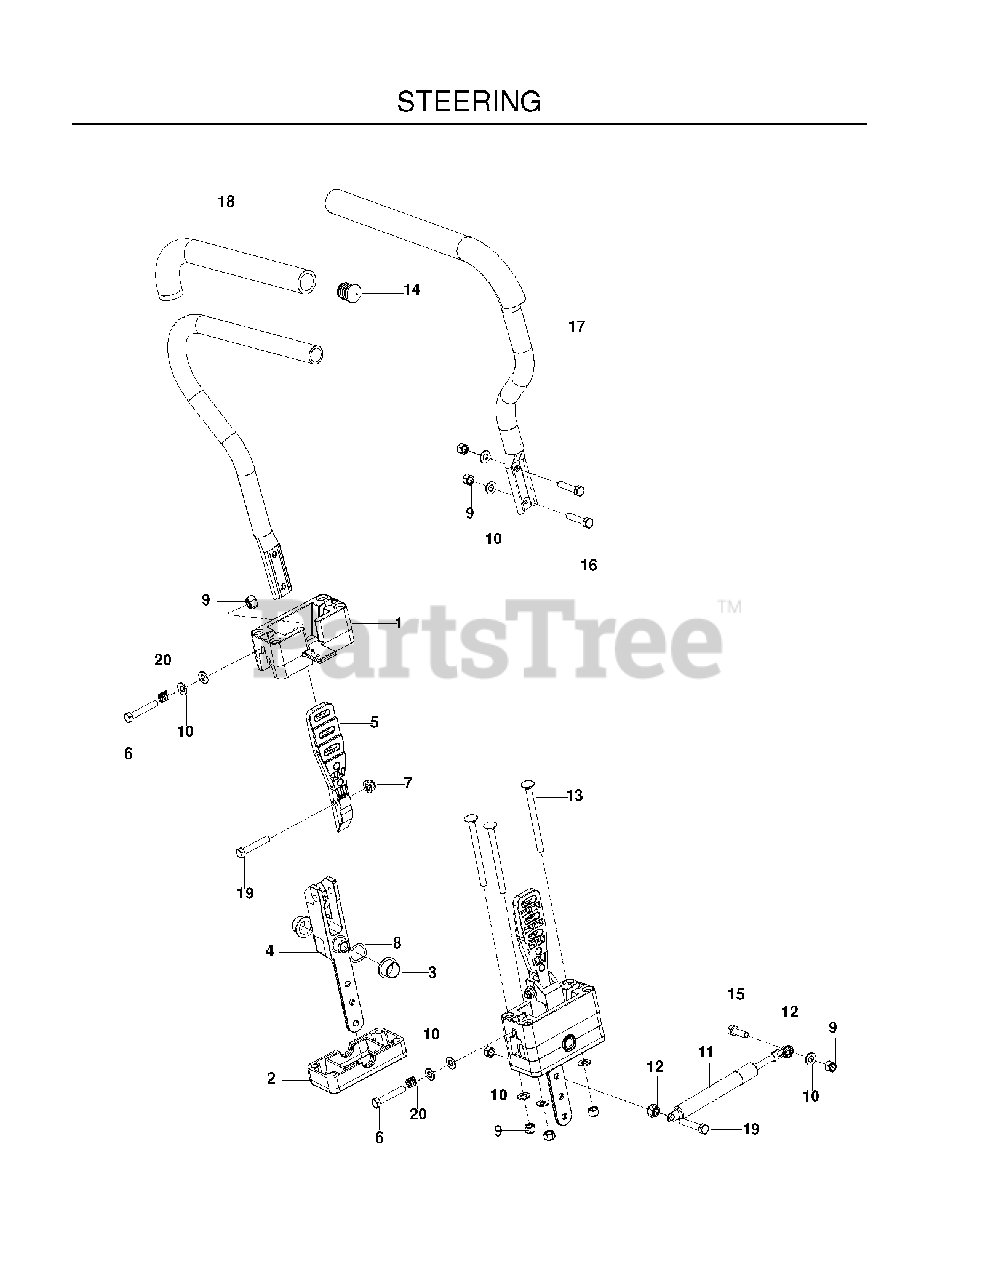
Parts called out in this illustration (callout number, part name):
1	BLOCK, UPPER
2	BLOCK, LOWER
3	BEARING, FLANGE
4	PIVOT.SECTION.DRIVE.CONTROL
5	MOUNT.HANDLE.CONTROL
6	HCS 5/16-18 X 2 TPBLT GR 5 ZD
7	5/16-18 NYLOC FLANGE NUT
8	WASHER, .825 X 1.087, WAVE
9	NUT 5/16 NYLOC
10	FLAT WASHER 5/16 SAE
11	DAMPENER
12	NUT 5/16C WHIZ
13	RHSNB 5/16-18 X 4 GR 5 ZD
14	END PLUG 15/16` (BLACK)
15	HCS 5/16C X 1
16	CAPSCREW 5/16 X 1/1/2 HEX HEAD
17	ASSEMBLY, DRIVE LEVER
18	GRIP, DRIVE LEVER
19	HCS 5/16C X 1 3/4
